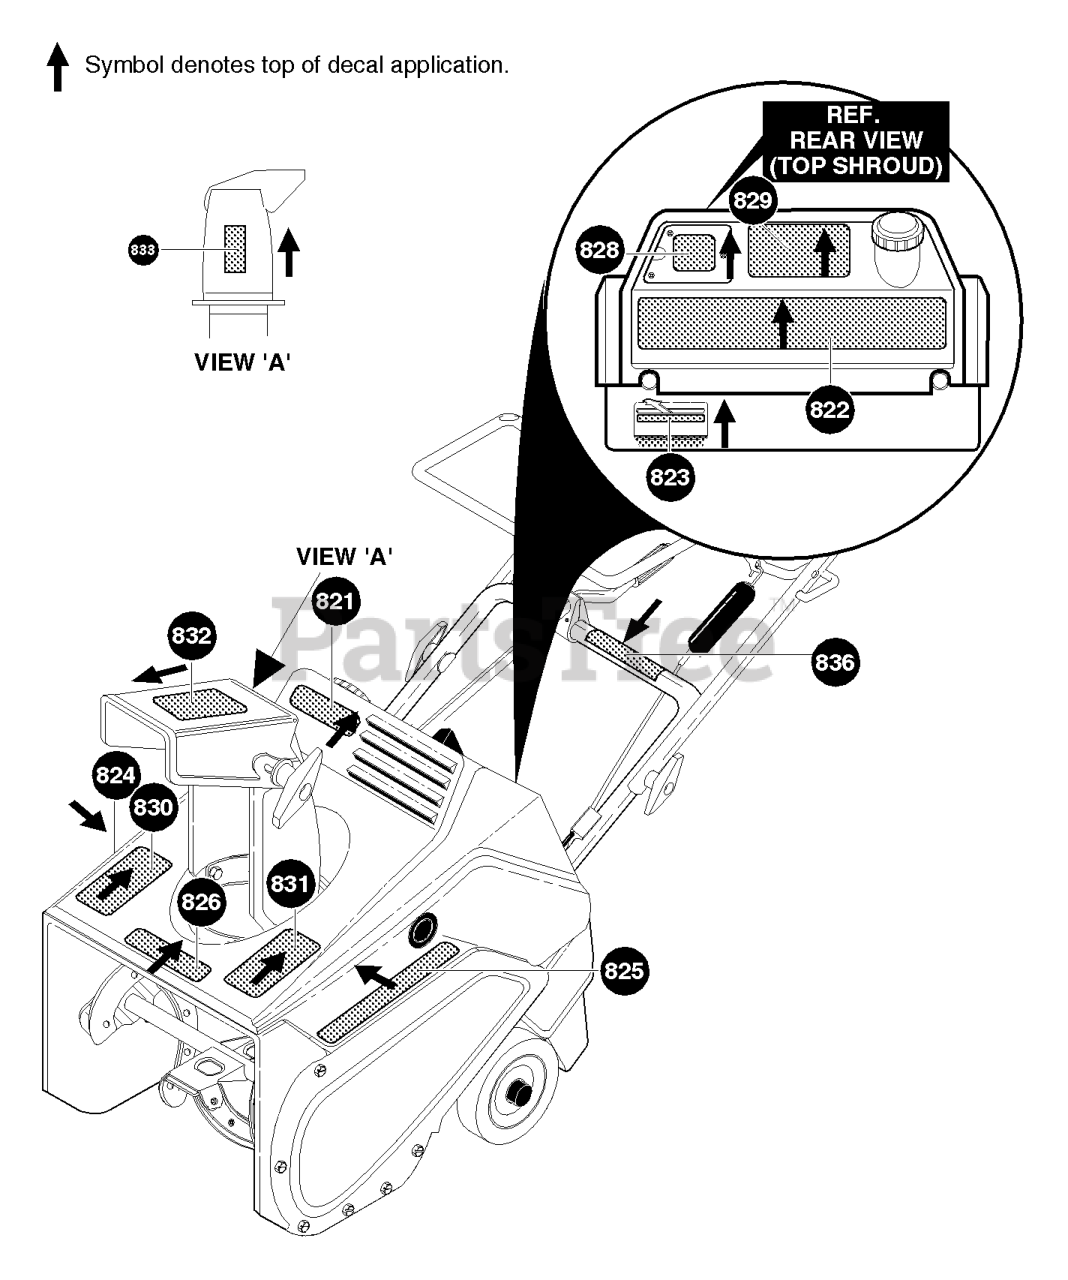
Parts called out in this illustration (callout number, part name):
821	DECAL, HUSQVARNA
822	DECAL, CONTROL PANEL
823	DECAL, OFF-CHOKE-ON
824	DECAL, SIDE PANEL
825	DECAL, ST521 LH SIDE PANEL
826	DECAL, HUSQVARNA TOP COVER
828	DECAL, FUEL MIX ENG/FR
829	DECAL, START INSTRU ENG/FR
830	DECAL, DANGER CHUTE
831	DECAL, DANGER AUGER
832	DECAL, HUSQ "CROWN"
833	DECAL, SAFETY INSTRU ENG/FR
836	DECAL, AUGER CONTROL BAR
